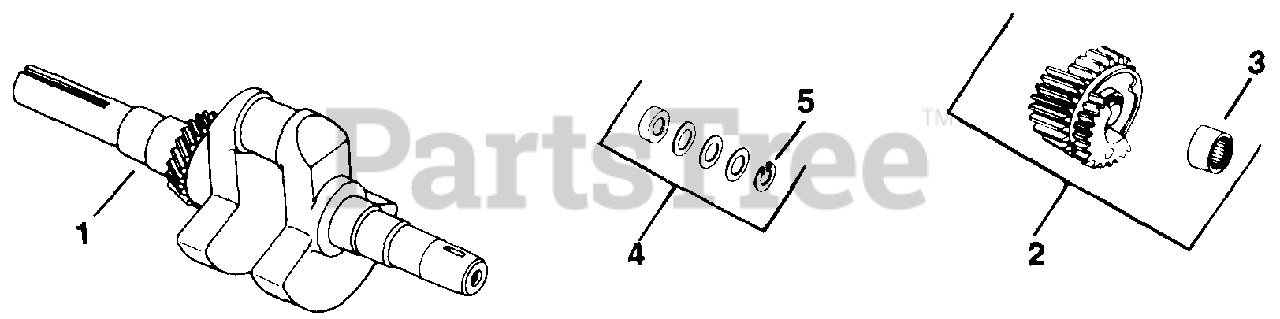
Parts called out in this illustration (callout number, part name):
1	CRANKSHAFT KIT
2	GEAR
3	BEARING
4	KIT, SPACER
